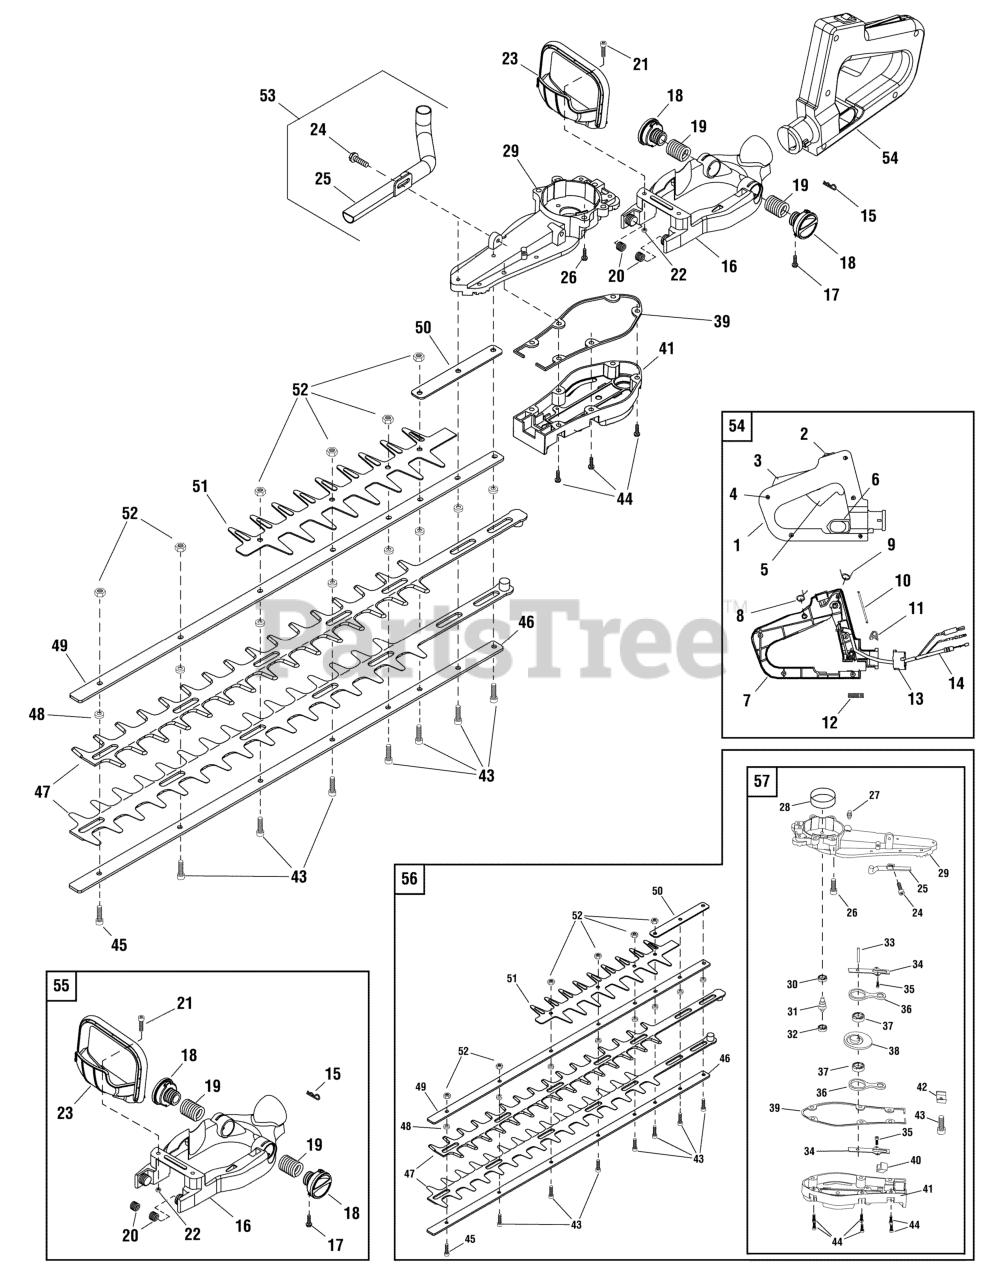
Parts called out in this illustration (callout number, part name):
1	HANDLE, Left
2	STOP BUTTON, Complete
3	LEVER, Interlock
4	SCREW, Self Tapping, ST4.2 x 19
5	TRIGGER, Throttle
6	HANDLE, Lock
7	HANDLE, Right
8	SPRING, Self Lock
9	SPRING, Handle
10	ROD, Lock
12	SPRING
13	COUPLING
14	CABLE, Complete
15	HOLDER, Clip
17	BOLT, M5 x 16
18	COVER, Damping Spring
19	DAMPING SPRING A
20	DAMPING SPRING B
21	BOLT, M5 x 45
22	NUT, Hex, M5
23	HANDLE, Front
24	BOLT, M5 x 16
25	TUBE, Exhaust
26	BOLT, M5 x 20
27	CUP, Fuel
28	CLUTCH DRUM, Complete
29	GEAR BOX CASE
30	BEARING, GB276 6001-2RS
32	BEARING, 628
34	WASHER
35	BOLT, M4 x 6
36	ROD, Connect
37	BEARING, 61805-2RZ
38	GEAR, Crank
39	GASKET
40	GASKET
41	COVER, Gear Box
42	GUIDE PAD
43	BOLT, M5 x 25
44	BOLT, M5 x 16
45	BOLT, M5 x 20
46	PLATE, Blade Holder
47	BLADE, Set of 2
48	SPACER
49	BRACKET, Blade
50	ENHANCE PLATE
51	GUARD, Blade
52	NUT, M5
53	KIT, Exhaust Tube
54	HANDLE ASSEMBLY, Complete
55	KIT, Base Assembly
56	KIT, Gearbox & Blade
57	KIT, Gearbox
